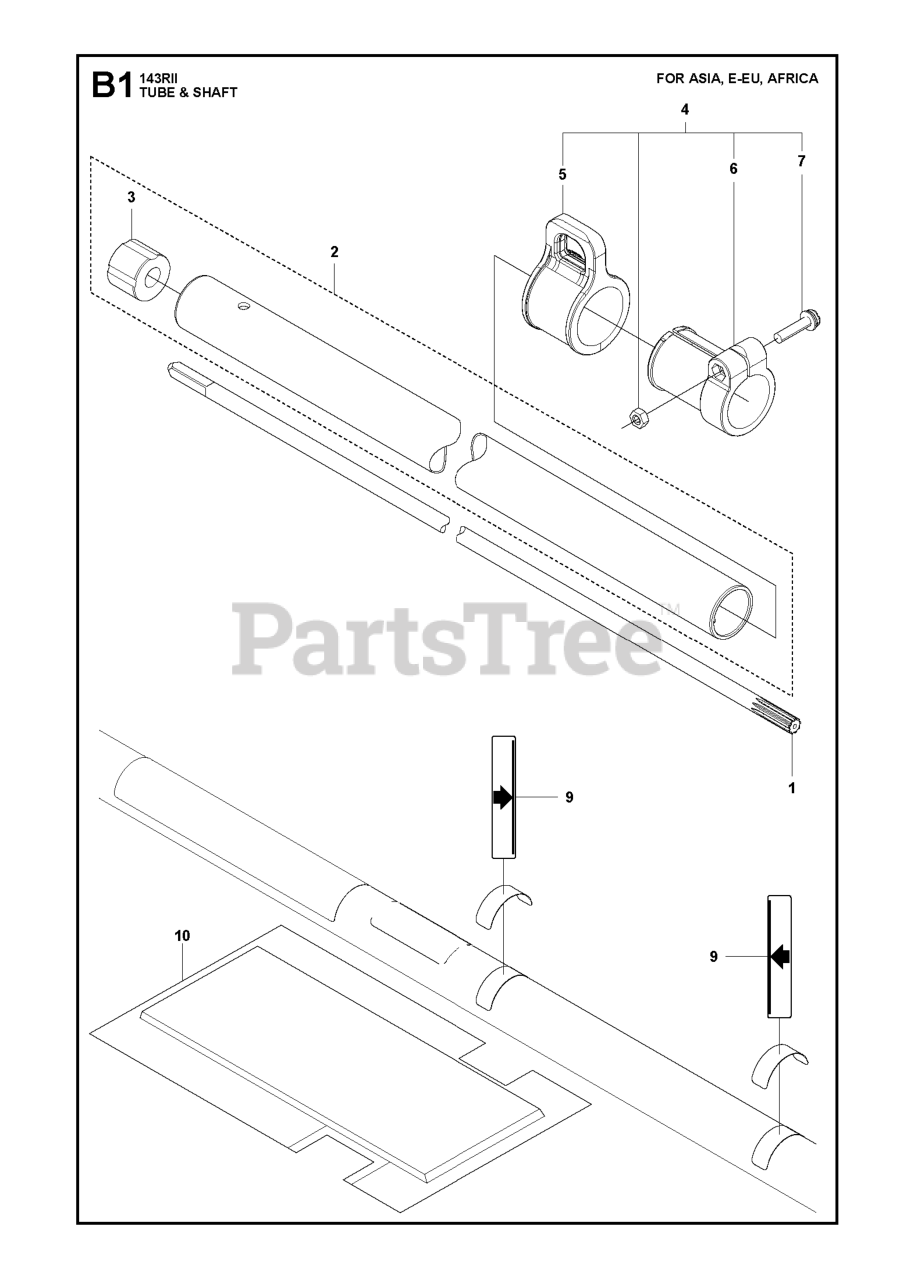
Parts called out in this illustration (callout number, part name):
1	DRIVE SHAFT
2	PIPE COMP.
9	LABEL
10	PROTECTOR (RPLS 405017110)
